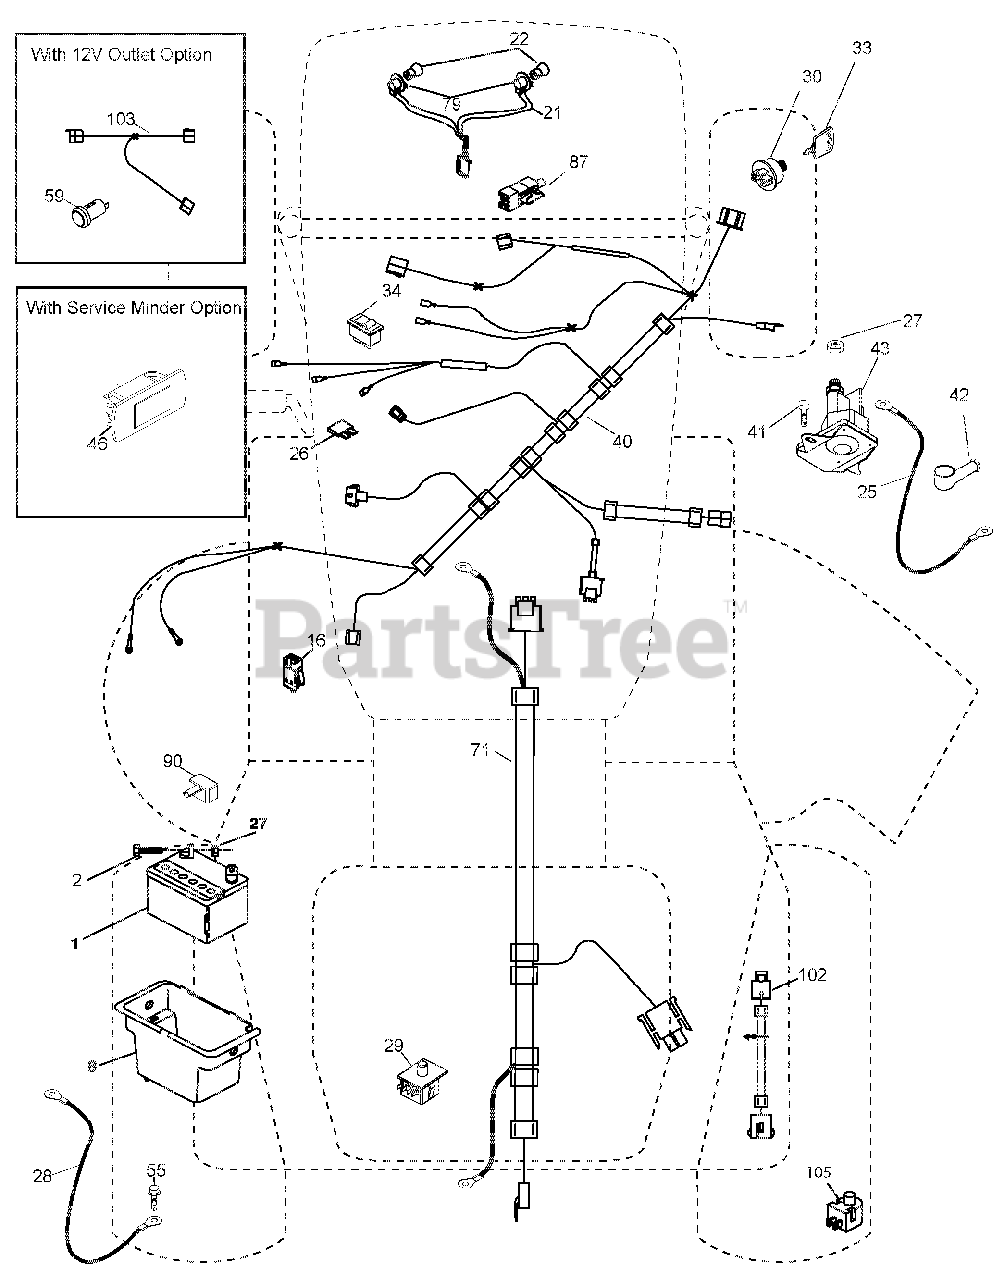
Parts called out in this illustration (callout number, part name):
1	BATTERY.12.VOLT.28.AMP.WET
2	BOLT.HEX.HD.1/4-20UNC X 3/4
8	BOX.BATTERY.MNT.REAR.LT.TEX.BL
16	SWITCH.INTERLOCK.NONO.GRAY
21	HARNESS ASM.LIGHT.22"(4152J)
22	BULB.LIGHT.#1156
25	CABLE.STARTER.6GA.BL/RED.14.5"
26	FUSE.20 AMP.
27	Nut, Keps Hex 1/4-20 unc
28	CABLE.BLACK.22"REAR BATT.TEX
29	SWITCH.SEAT.DP.W/ROS
30	SWITCH.IGN.DLTA.P-IN.ROS
33	KEY/CHAIN.BLISTER PACK.GEN.CE
34	SWITCH.LIGHT/RESET.B/B/RED.
40	HARNESS.IGN.DASH.CBL.YTGT.PRED
41	Screw 1/4-20 x 1/2
42	COVER.TERMINAL.RED
43	SOLENOID.W/BRASS PLUNGER.2005
55	SCREW.5/16-18X3/4.SMGML.TAP/R
71	HARNESS.IGN.CHASS.TEX.REAR.BAT
79	SOCKET ASM.BULB.TWISTLOCK
87	SWITCH.INTRLCK.CLUTCH.CABLE.TX
90	COVER.TERMINAL.BATTERY.RR.TEX
102	PIGTAIL REV. GT VATR
105	SWITCH.REVERSE.TT.PEDAL CONTRO
